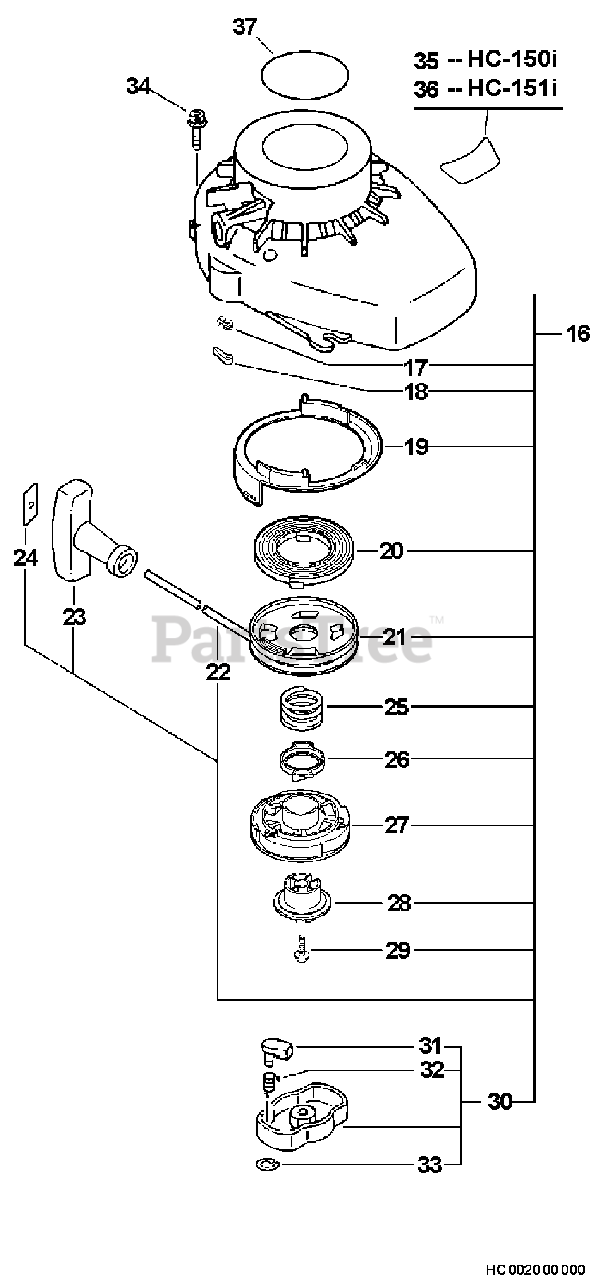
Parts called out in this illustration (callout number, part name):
16	STARTER ASSY - GRAY
18	PAWL, STARTER
19	CASE, STARTER
20	SPRING, RECOIL
21	PULLEY, STARTER
22	ROPE, STARTER
23	GRIP, STARTER
24	RETAINER, ROPE
25	SPRING, RETURN
26	PAWL, STARTER
27	SPRING ASSY
28	PLATE, CAM
30	PAWL ASSY, STARTER
31	PAWL, STARTER
32	SPRING, RETURN
33	E-RING 4
34	BOLT 4×16
35	LABEL, MODEL
36	LABEL, MODEL
